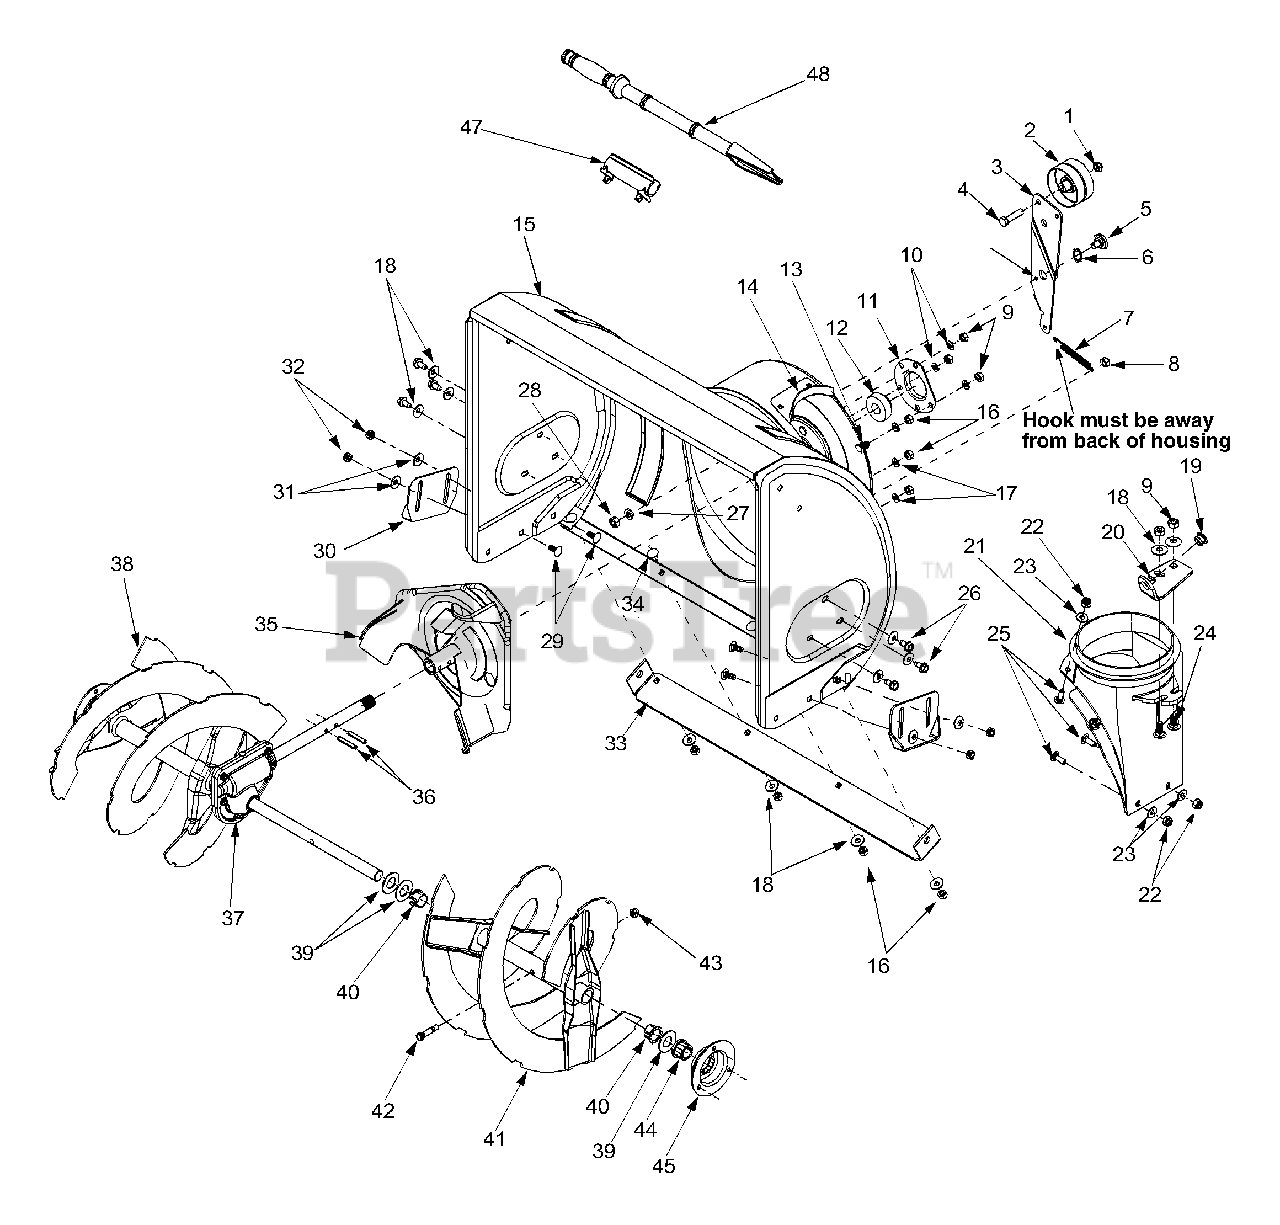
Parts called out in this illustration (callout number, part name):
1	Lock Jam Nut 3/8-24
2	Flat Idler
4	Hex Cap Screw 3/8-24 x 1.50
5	Shoulder Screw
6	Wave Washer
7	Extension Spring
8	Hex Nut 5/16-18
9	Hex Nut 5/16-18
10	Lock Washer 5/16
11	Housing
12	Ball Bearing
13	Carriage Bolt 5/16-18
17	Lock Washer 5/16
18	Bell Washer
19	Bushing
21	Chute Adapter
22	Hex Lock Nut 1/4-20
23	Flat Washer
24	Carriage Bolt
25	Carriage Screw 1/4-20 x .75
26	Hex Washer Screw 5/16-18
27	Lock Washer 3/8
28	Hex Nut 3/8-16
29	Carriage Bolt 5/16-18 x .75
31	Bell Washer
32	Hex Nut 5/16-18
34	Carriage Bolt 5/16-18 x .62
37	22" Gear Assembly
40	Flange Bushing
42	Shear Bolt 5/16-18 x 1.5
43	Lock Nut 5/16-18
44	Hex Flange Bearing
47	Clean-Out Tool Mount
48	Clean-Out Tool
